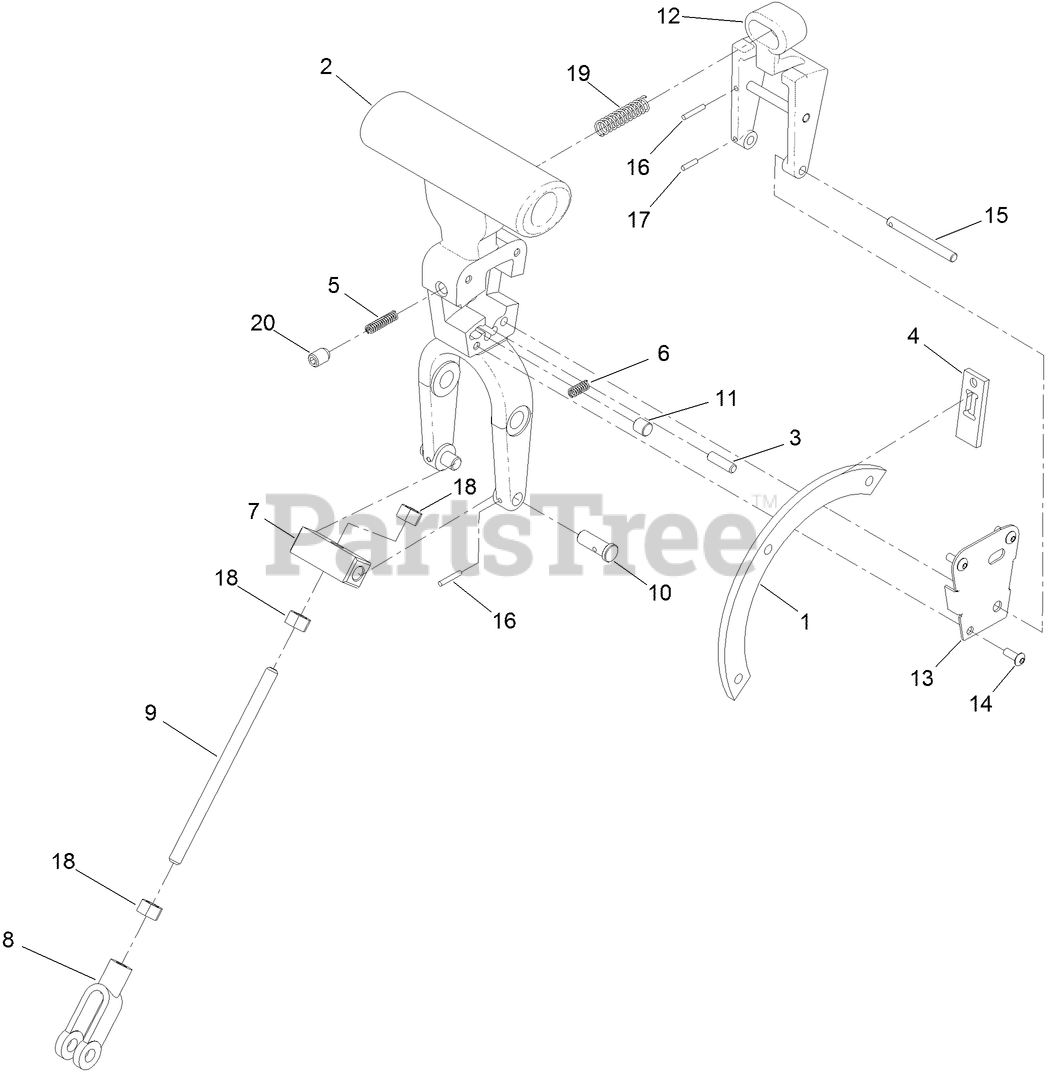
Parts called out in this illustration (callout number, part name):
1	GUIDE-LOCKING, PITCH
2	HANDLE-PITCH
4	PLATE-LOCKING, PITCH
5	SPRING-COMPRESSION
6	SPRING-COMPRESSION
7	SWIVEL-ROD, LINKAGE
8	YOKE-LINKAGE, BRAKE
9	ROD-LINKAGE
10	PIN-SWIVEL, LINKAGE
12	HANDLE-TRIP
13	COVER-HANDLE, INSPECTION
14	SCREW-HSBH
15	PIN-RELEASE, PIVOT
18	NUT-HEX
19	SPRING-COMPRESSION
20	SCREW-SET, HSH
